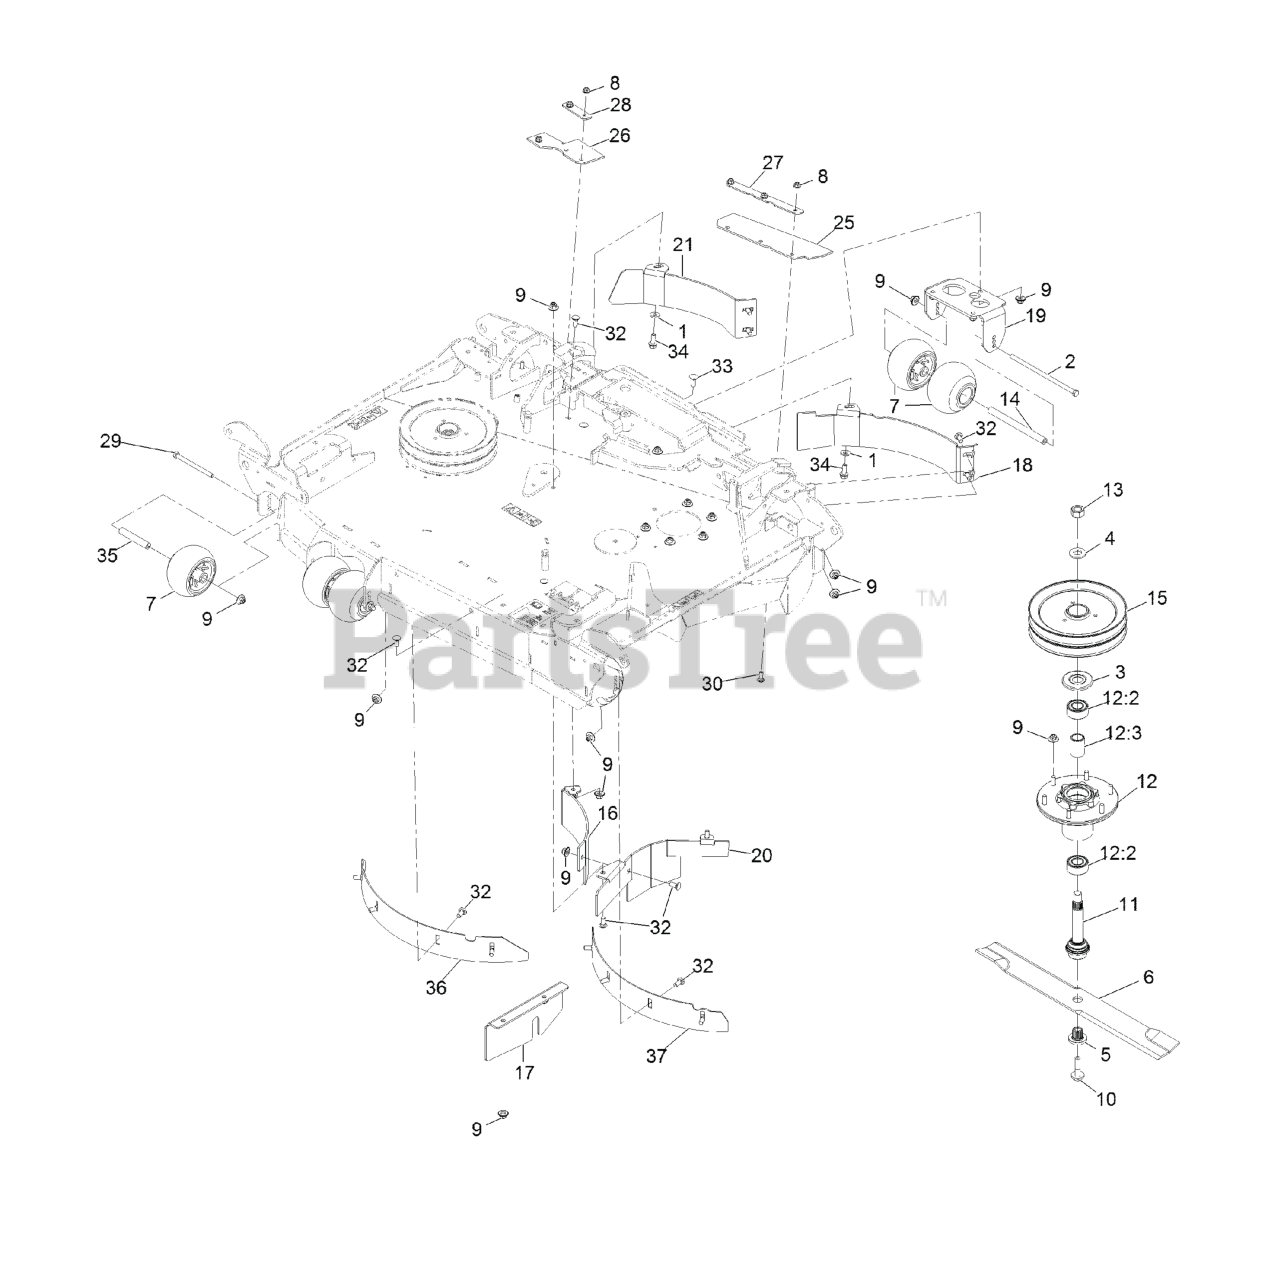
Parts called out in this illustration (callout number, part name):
1	WASHER-BELLEVILLE
2	SCREW-HH
3	GUARD-BEARING, TOP
5	BUSHING,SPLINED
7	ROLLER-SCALP, ANTI
8	NUT-HF, NI
9	Nut-Nyloc 3/8-16 Flg
10	SCREW,SEMS 1/2-20 X 2.19
11	ASM-SPINDLE AND SEAL
12	ASM-CUTTER HSG
12:2	BEARING-3205 TRASHGUARD
12:3	SPACER-BEARING
13	NUT-HEX
14	SPACER-WHEEL
15	SHEAVE-DOUBLE 96RD
16	BAFFLE-CENTER, REAR (RH)
17	PLATE-BLOCK, FRONT
18	BAFFLE-BLOCK, LH CTR
19	BRACKET-ANTISCALP, REAR
20	BAFFLE-CENTER
21	BAFFLE-BLOCK, RH CTR
25	Flap-Discharge
26	Flap-Discharge
27	Support-Flap
28	Support-Flap, RH
29	SCREW-HH
30	SCREW-CARR
32	BOLT-CARR
33	BOLT-CARR
34	SCREW-HHF
35	SPACER-WHEEL SHORT
36	BAFFLE-DEPTH, LH
37	BAFFLE-DEPTH, RH
